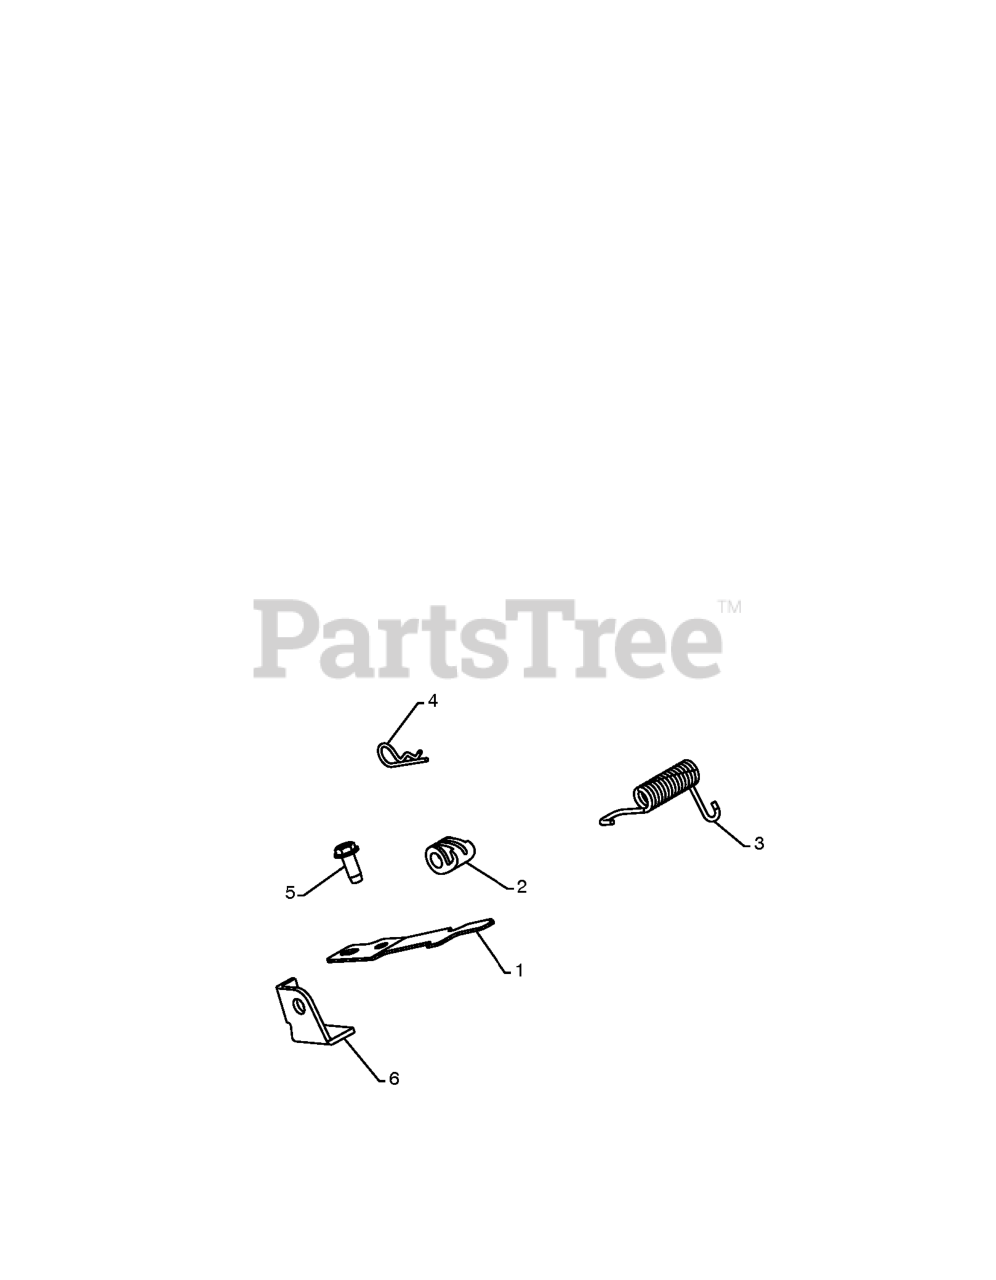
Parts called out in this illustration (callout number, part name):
1	RP SPRING.INTERLOCK
2	CAM.INTERLOCK.RELEASE
3	RP SPRING, TORSION
4	SPRING RETAINER
5	SCREW 14-20 X 5/8
6	STOP.INTERTLOCK.SPRING.
